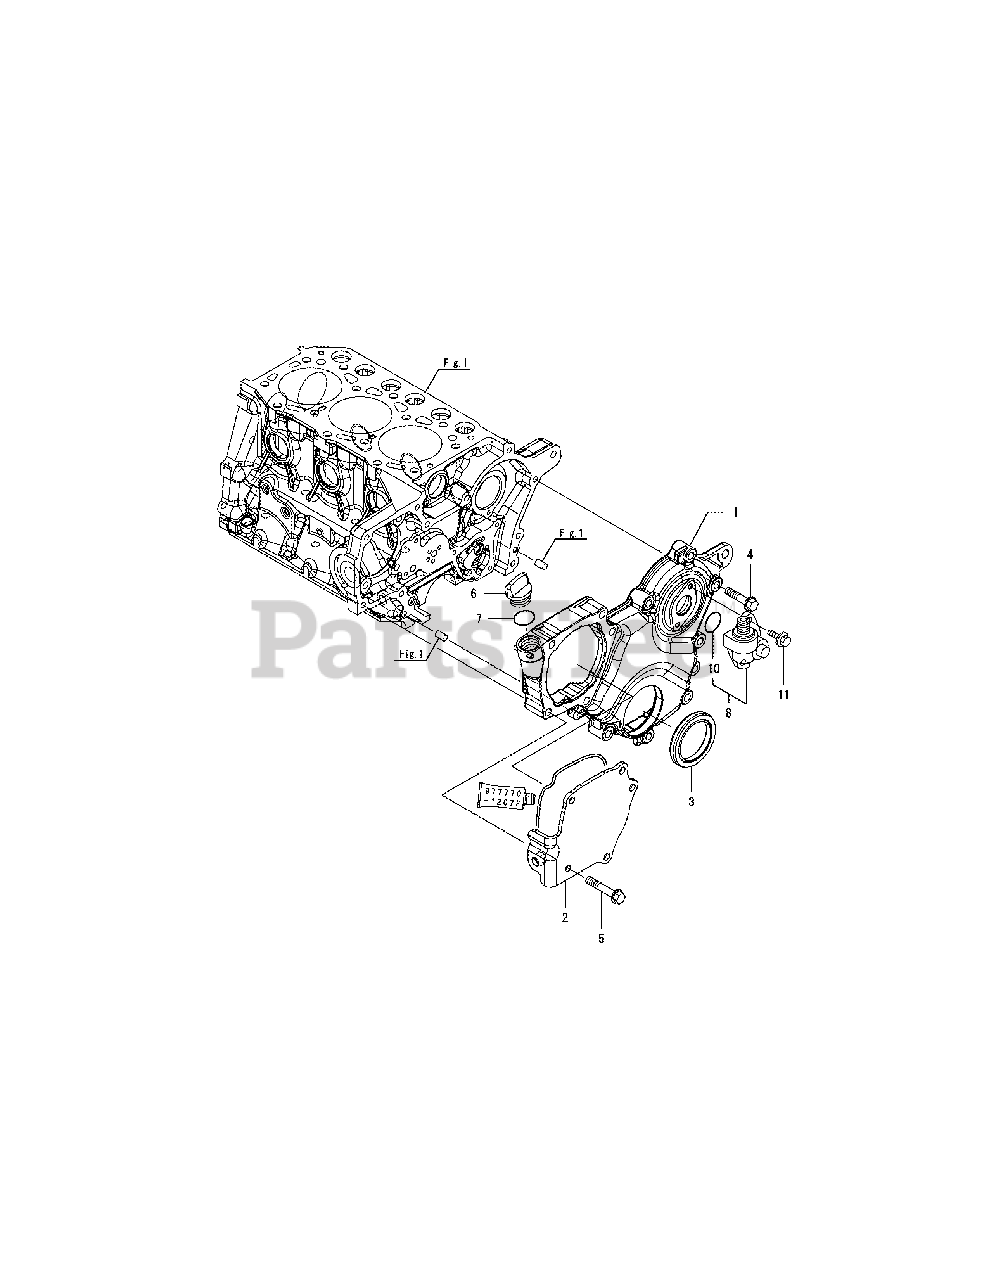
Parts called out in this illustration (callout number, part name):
1	CASE GEAR,TACHO
2	COVER, PUMP TIMING
4	BOLT M 8X 35 PLATED
5	BOLT M 8X 45 PLATED
6	CAP, L.O.SUPPLY
7	O-RING 1A P-18.0
10	O-RING 1A S-24.0
11	BOLT M 6X 16 PLATED
